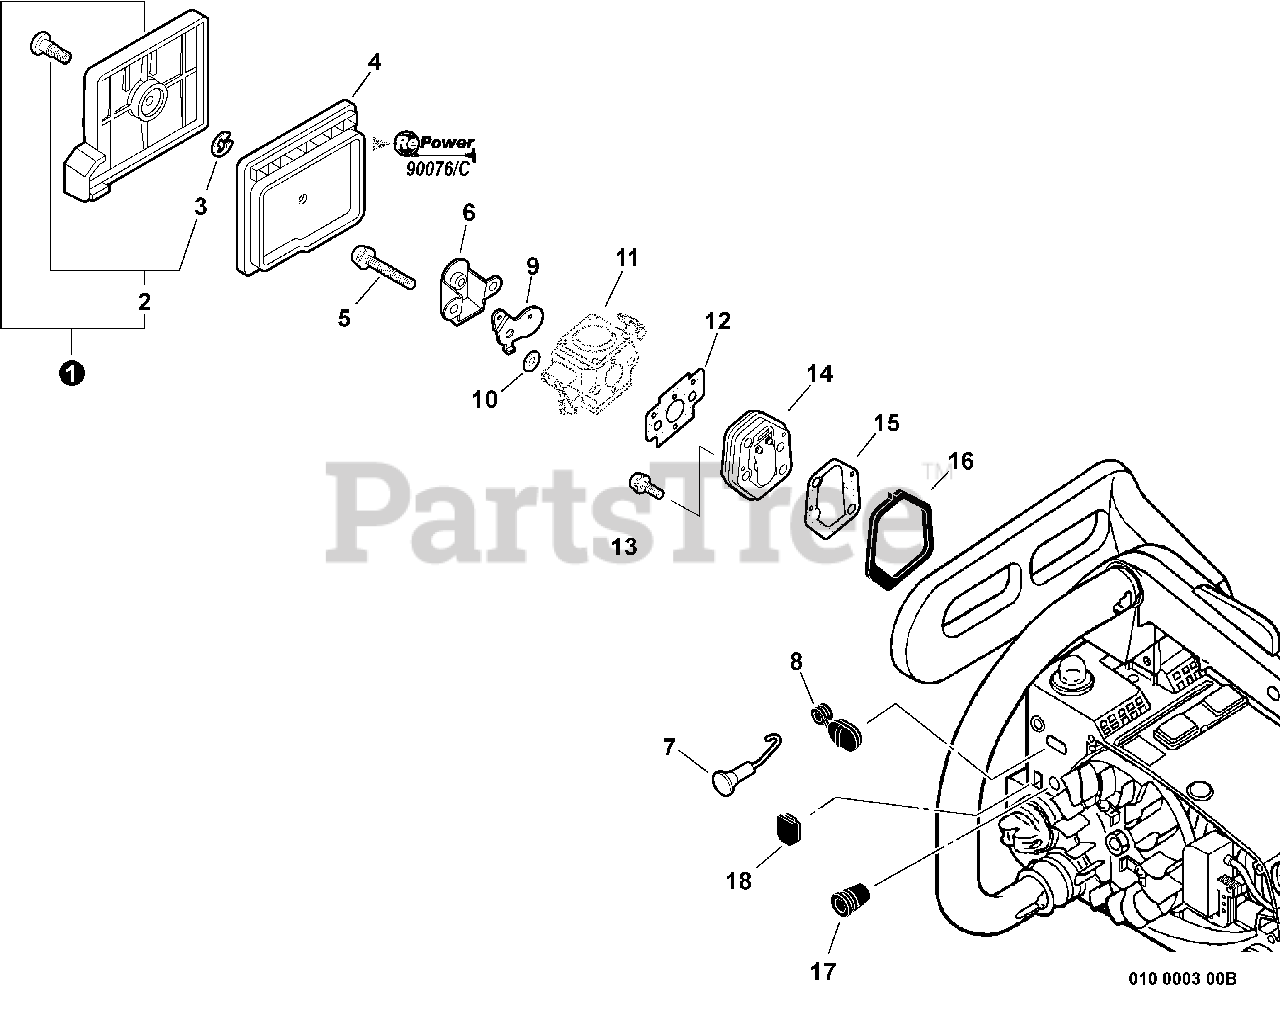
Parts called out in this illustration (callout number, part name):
1	AIR FILTER COVER ASSY
2	THUMBSCREW
3	RING, RETAINING - 4
4	FILTER, AIR
5	SCREW - 5X45
6	PLATE, PREVENT
7	ROD, CHOKE
9	SHUTTER, CHOKE
10	WASHER
11	CARBURETOR
12	GASKET, INTAKE
13	SCREW - 5X18
14	INSULATOR KIT
15	GASKET, INTAKE
16	SEAL
19	RePower TUNE-UP KIT
